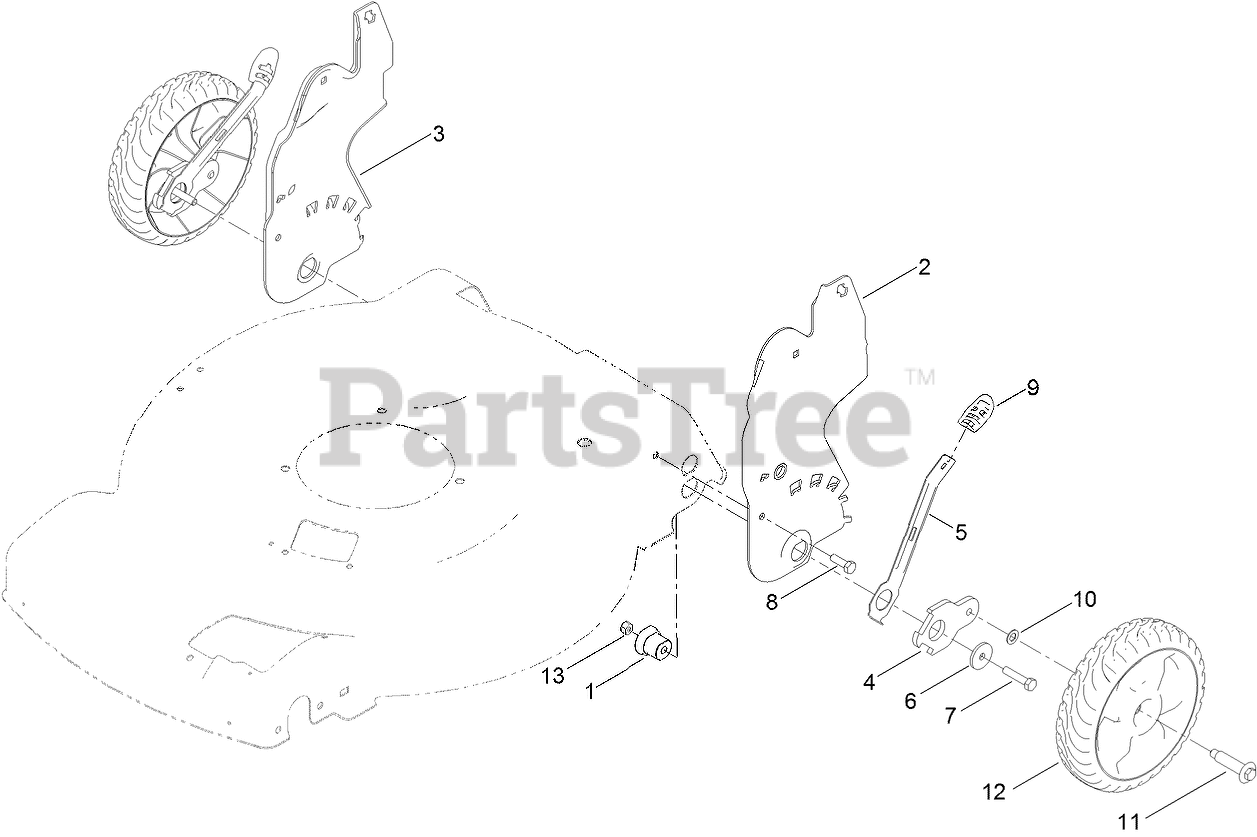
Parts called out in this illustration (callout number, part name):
1	BUSHING-MOUNT, HOC
2	PLATE-HOC, LH
3	PLATE-HOC, RH
4	ARM-PIVOT, REAR
5	ARM-SPRING, REAR
6	WASHER-FLAT
7	SCREW-HH
8	SCREW-HH
9	KNOB-LEVER, HOC
10	WASHER
11	BOLT-SHOULDER
12	81IN WHEEL ASM
13	NUT-LOCK, NI
